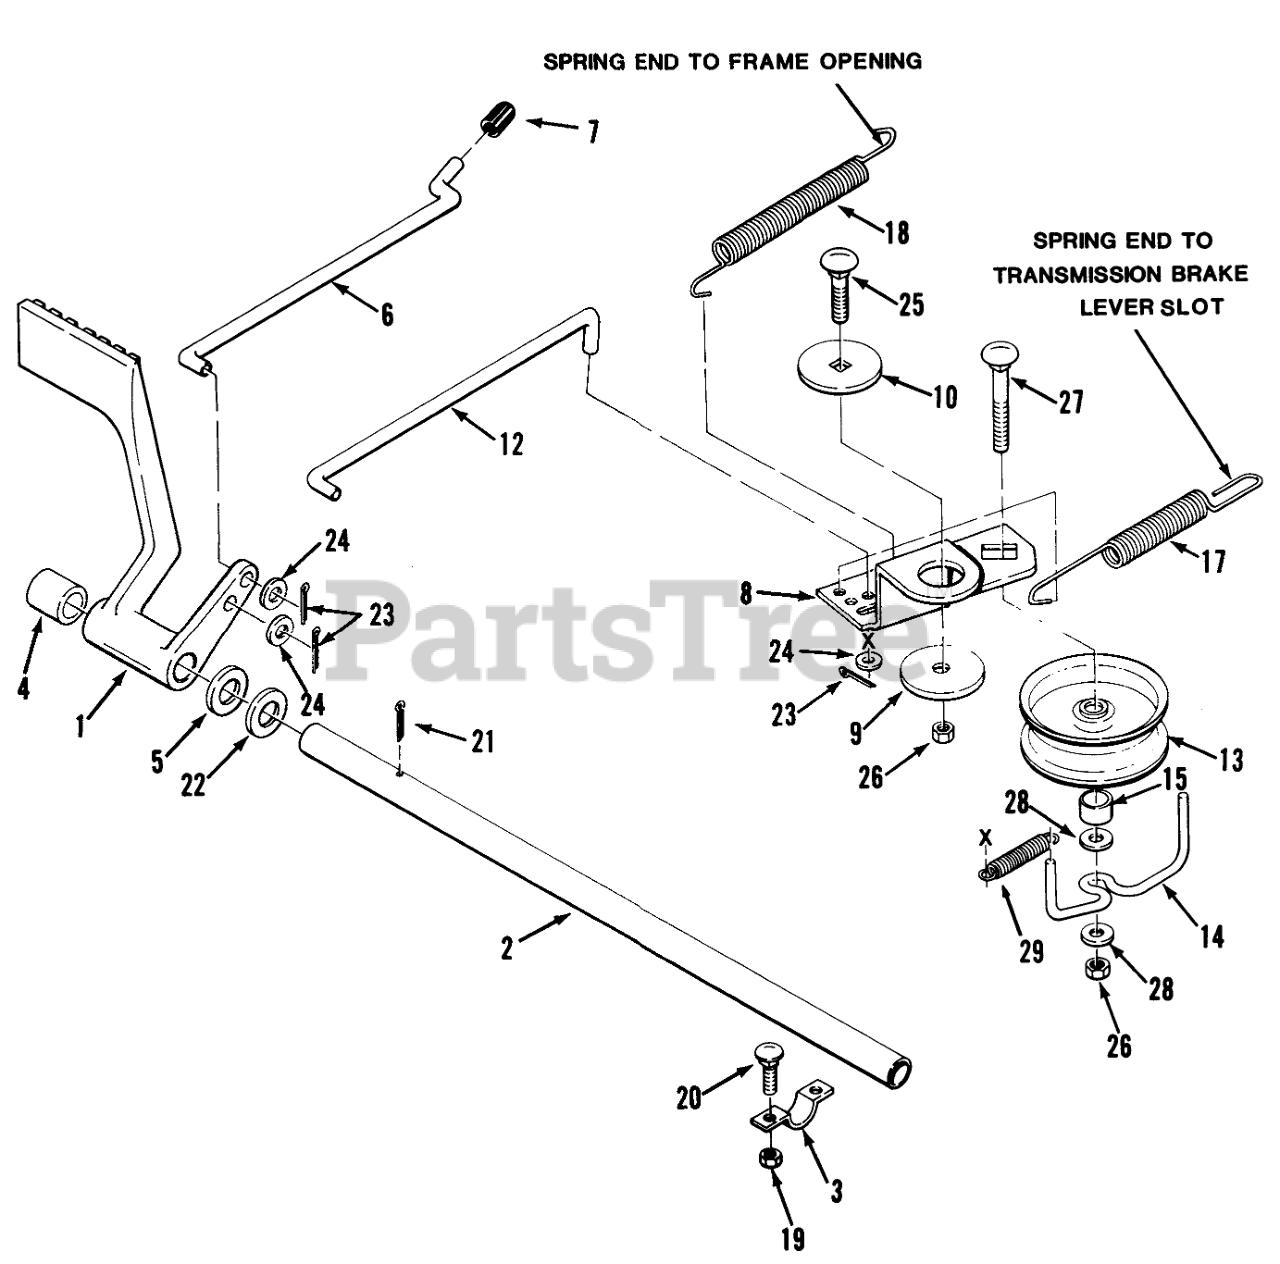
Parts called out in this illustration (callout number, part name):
1	PEDAL BRAKE R
2	SHAFT PEDAL
3	CLAMP
4	SPACER
5	WASHER-WAVE
6	Lock Rod
8	ARM-IDLER R
9	BUSHING
10	WASHER-BEARING
12	ROD-CLUTCH/BRAKE B
13	PULLEY IDLER
14	GUIDE-BELT
15	SPACER
17	SPRING - BRAKE
18	SPRING - CLUTCH
19	NUT-LOCK, NI
20	SCREW-CARR
21	PIN-COTTER
22	Washer
23	PIN-COTTER
24	WASHER-PLAIN
25	BOLT-CARR
26	NUT-LOCK, NI
27	SCREW-CARR
28	WASHER-FLAT
29	EXTENSION-SPRING
